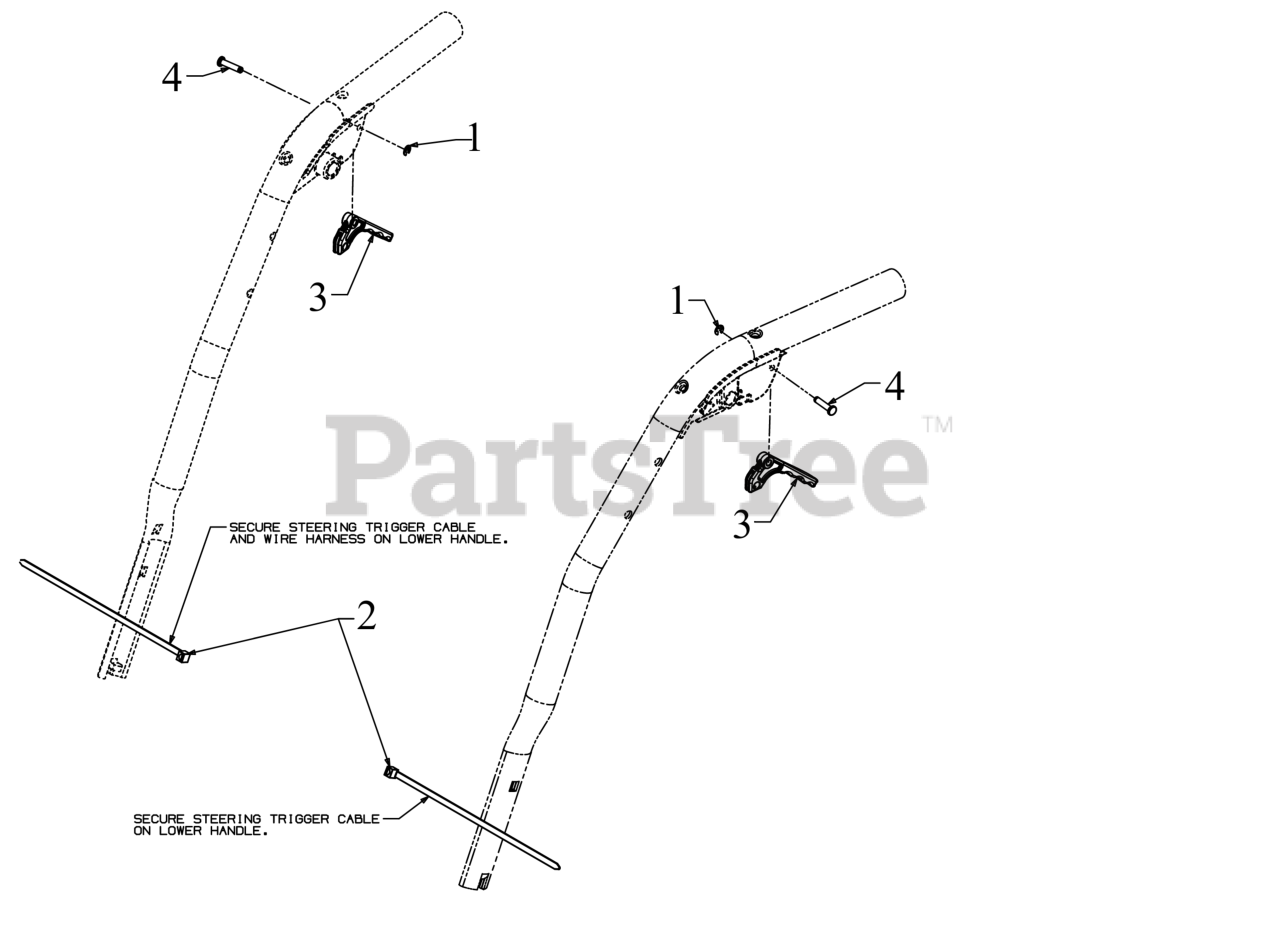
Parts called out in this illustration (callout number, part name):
1	E-RING
2	7" CABLE TIE
3	STEERING CONTROL TRIGGER
4	STEERING TRIGGER PIN 3/16
